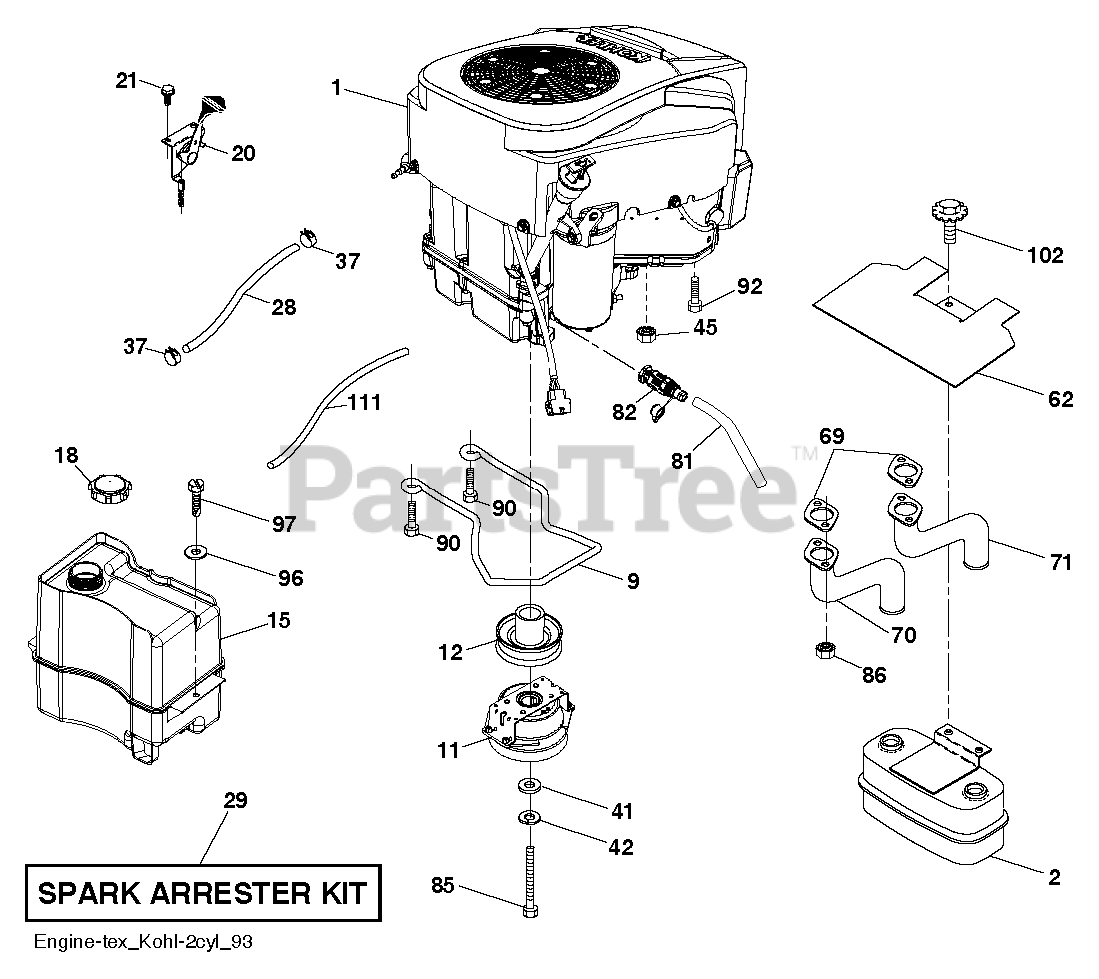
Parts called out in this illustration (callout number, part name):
2	MUFFLER.ASM.TWIN.MNTG.BRACKET
11	CLUTCH.OGURA.5.0PD.GT1.5A-EH07
12	PULLEY.ENGINE.TUFFTORQ
18	CAP ASM.FUEL.2.25"FR.
20	THROTTLE CONTROL
28	LINE.FUEL.20"FRONT.EMI
29	KIT.SPARK ARRESTOR 794945 B&S
37	HOSE CLAMP
62	SHIELD.HEAT.MUFFLER
69	GASKET.EXHAUST.KOHL.CV18-CV26
70	PIPE.EXHAUST.LH.CV18/20
71	PIPE.EXHAUST.RH.CV18/20
81	TUBE, DRAIN OIL ASM.
82	VALUE.OIL.DRAIN
85	BOLT.HEX.7/16-20X3.75.GR5.RED
86	NUT.HEX.FLANGE.TOPLOCK
90	SCREW 3/8-16X1
92	SCREW 3/8-16X1
97	SCREW HEXWSHR 1/4-20X3/4
102	SCREW
111	TUBE.PURGE.FUEL.1875
